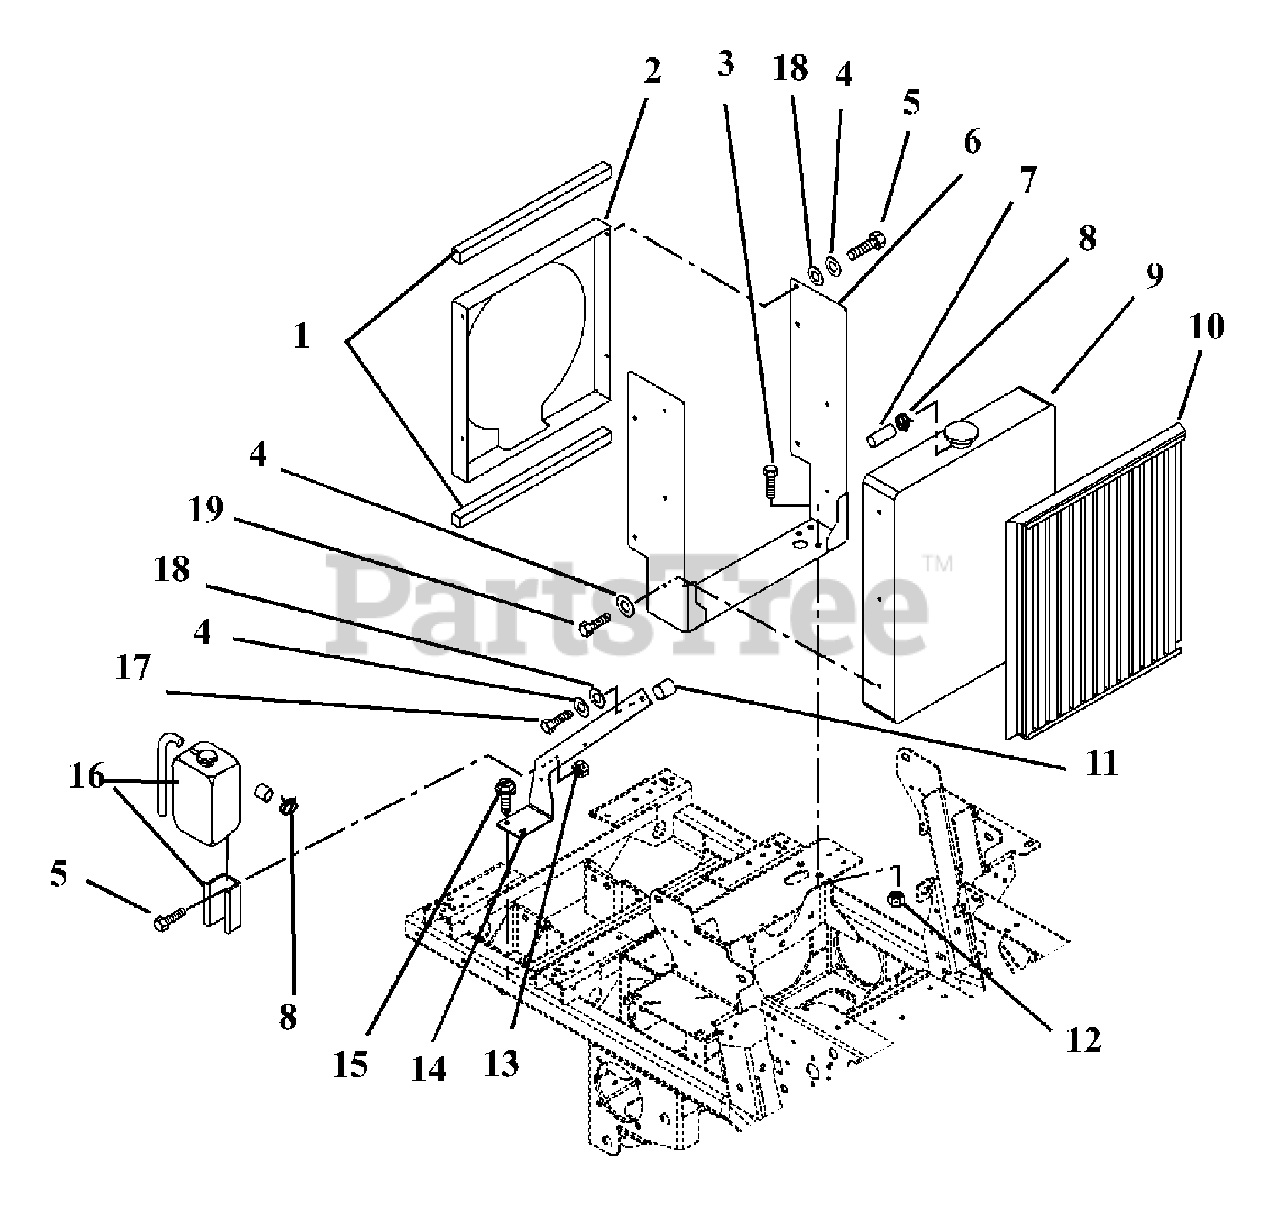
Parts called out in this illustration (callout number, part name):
1	SEAL, TRIM-LOK BULK .06 BBL 1'
2	WMT, RADIATOR SHROUD
3	@BLT-HEX .38-16X1.00 GR5 YWZC
4	@WSHR-LK .25X.062 REG YWZC
5	@BLT-HEX .25-20X.75 GR5 YWZC
6	WMT, RADIATOR MOUNTING BKRT
7	GAS LINE-BULK 1/4" I.D.
8	CLAMP-HOSE WIRE .490/.510X.116
9	Radiator
10	SCREEN, RADIATOR (DIESEL)
11	SPACER .328 X .76 X 1.01
12	@NUT-LK-TOP-FLG .38-16 YWZC
13	@NUT-LK-TOP-FLG .25-20 YWZC
14	BRKT, OVERFLOW MOUNTING - BLK
15	@SCR-TAP .38-16X.75 HWH TR YWZ
16	Reservoir Overflow
17	@BLT-HEX M6-1.00X45 YWZC
18	@WSHR-FL-STL.281X.62X.065 YWZC
19	@BLT-HEX M6-1X16 YWZC
